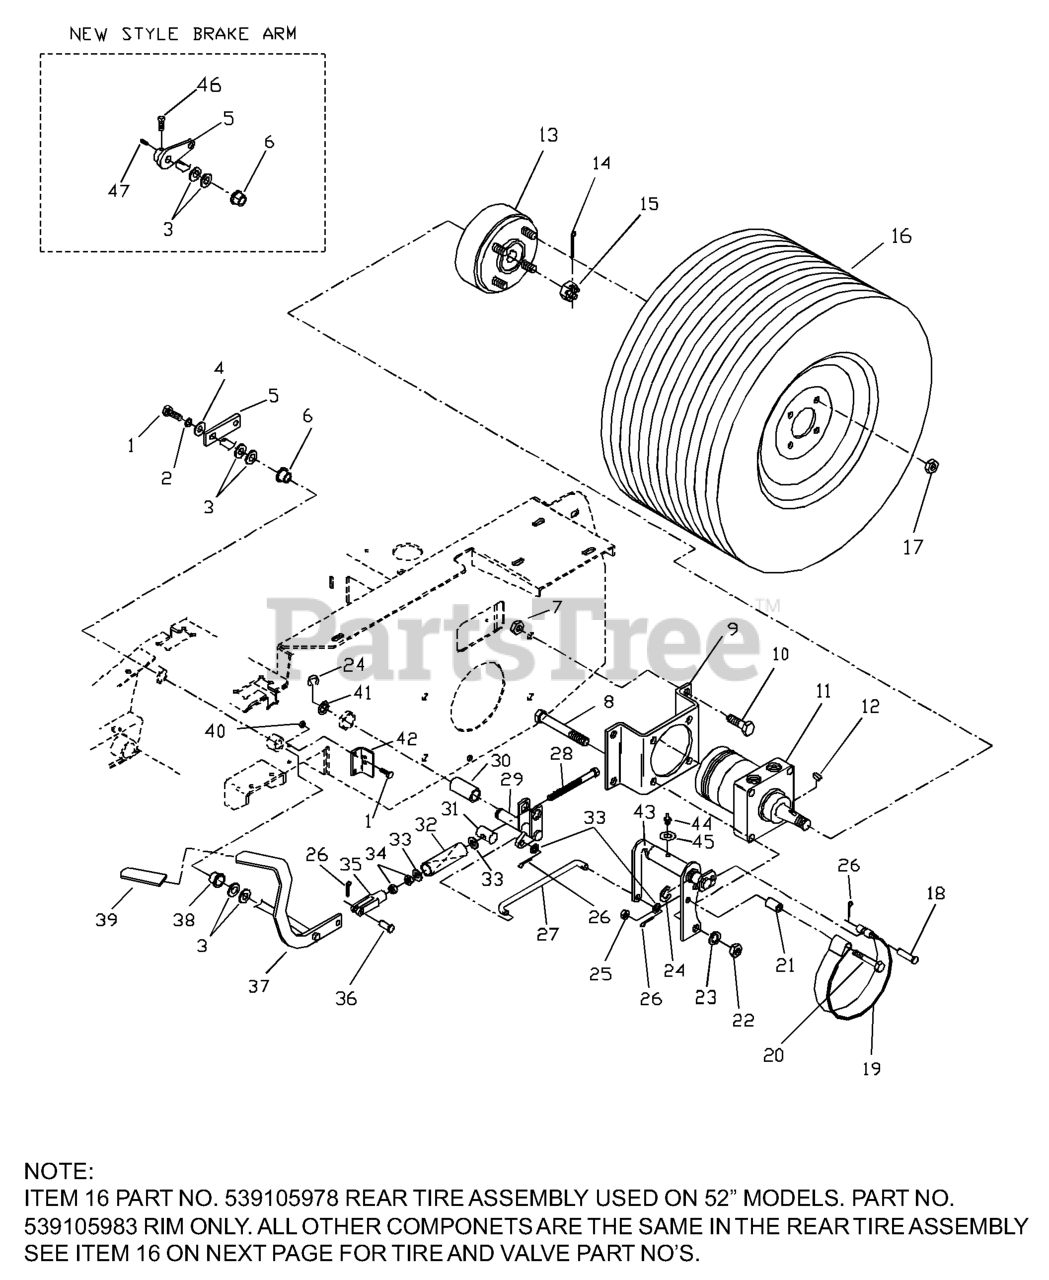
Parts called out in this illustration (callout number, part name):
1	HCS 1/4C X 3/4 HCS
2	LOCKWASHER 1/4"
3	WASHER, 7/16 DISC SPRING
4	WASHER 1/4 FLAT
5	ARM, PARK BRAKE
5	BRAKE ARM WELDMENT
7	NUT 1/2-13 HEX NYLOC ZD
8	HCS 1/2C X 2 3/4
9	MOTOR STANDOFF - PAINTED
10	HCS 1/2C X 1 1/4 SERRATED HEAD
11	MB WHEEL MOTOR
12	WOODRUFF KEY
13	HUB W/BRAKE DRUM
14	COTTER PIN
15	CASTLE-NUT
16	WHEEL/TIRE.ASM.24X12-12.SILVER
16	TIRE.24X12-12.TURF.MASTER
16	12"RIM 2.5" NEG OFFSET 8.5" W
16	VALVE STEM TR-412
17	LUG NUT 1/2F
18	CLEVIS PIN, 3/8 X 1 1/2
19	BRAKE BAND
20	HCS 3/8 X 3 GD.8
22	NUT HEX 1/2
23	WASHER 1/2" SPLIT LOCK
24	E RING 3/4
25	NUT 3/8C CENTERBLOCK
26	RP_COTTER PIN 1/8 X 3/4
27	BRAKE LINKAGE, LT.
27	BRAKE LINKAGE, RT.
28	HCS 3/8F X SPECIAL
30	BRONZE BEARING
31	TRUNION PIN
33	WASHER 3/8 SAE FLAT
35	YOKE-3/8-24 PLTD
36	CLEVIS PIN 3/8 X 1 1/8
37	BRAKE LEVER WIDMT
39	GRIP, PARK BRAKE
40	NUT 1/4C CENTERLOCK
43	LT.BRAKE WLDMT
43	RT.BRAKE WLDMT
44	ZERK
46	SCREW 5/16C X 5/8 SQ HEAD
